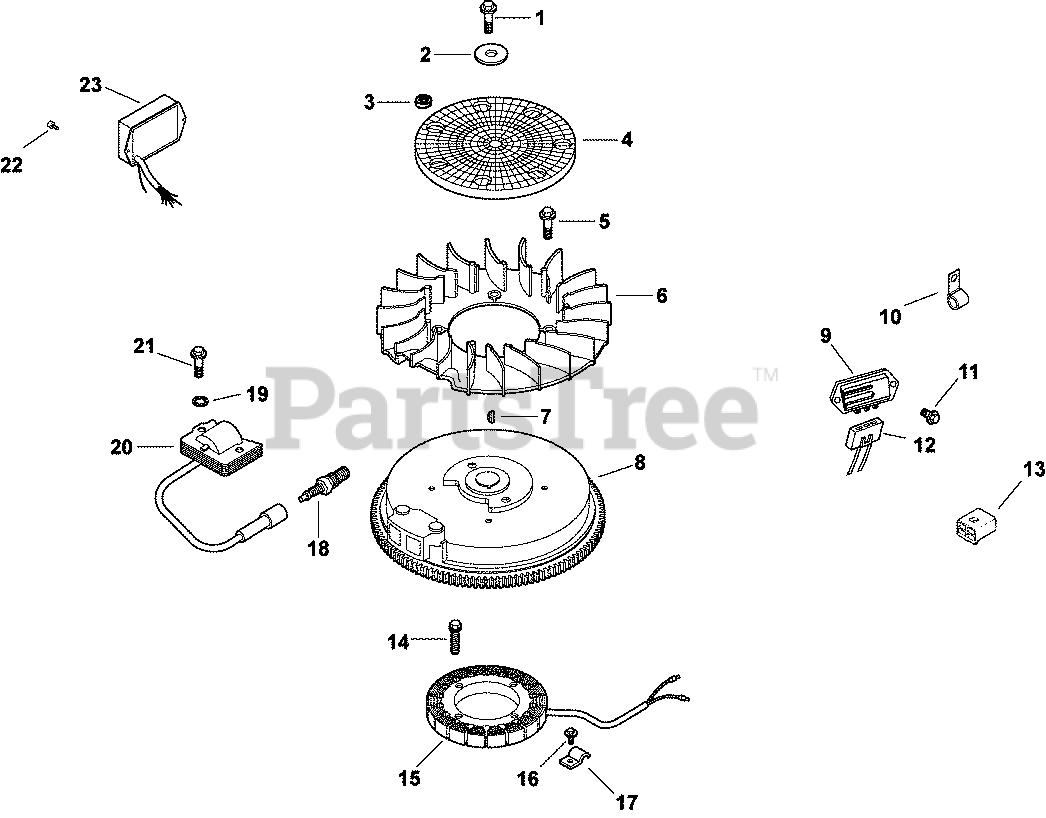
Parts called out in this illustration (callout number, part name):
1	SCREW, FLG M10X1.5X45 - (#25086361S)
2	WASHER, FLAT 13/32"
4	SCREEN, GRASS
5	BOLT, SHOULDER
7	KEY, 3/16" X 5/8"
8	FLYWHEEL - DISCONTINUED
9	REG/RECT-15 AMP (KM)-USE 41 403 10-S
10	CLIP, CABLE
11	SCREW, PHL HD #11-16X7/8"
12	CONNECTOR, BODY (KM)-USE 25 155 41-S
13	CONNECTOR
14	SCREW, M5X0.8X25 - (#25086402S)
15	KIT, 15 / 20 AMP STATOR
16	SCREW, FLG THD FRM M5X.8X10
18	PLUG, SPARK (STD)
19	WASHER, INT TOOTH LOCK 1/4"
20	MODULE, IGNITION
20	MODULE DSAI
21	SCREW, SCKT THRD FRMM5X0.8X20 - DISCONTINUED
22	SCREW, PHL THD FRM M4.2X13
23	MODULE, DIGITAL SPD ADV-USE 12 707 01-S
